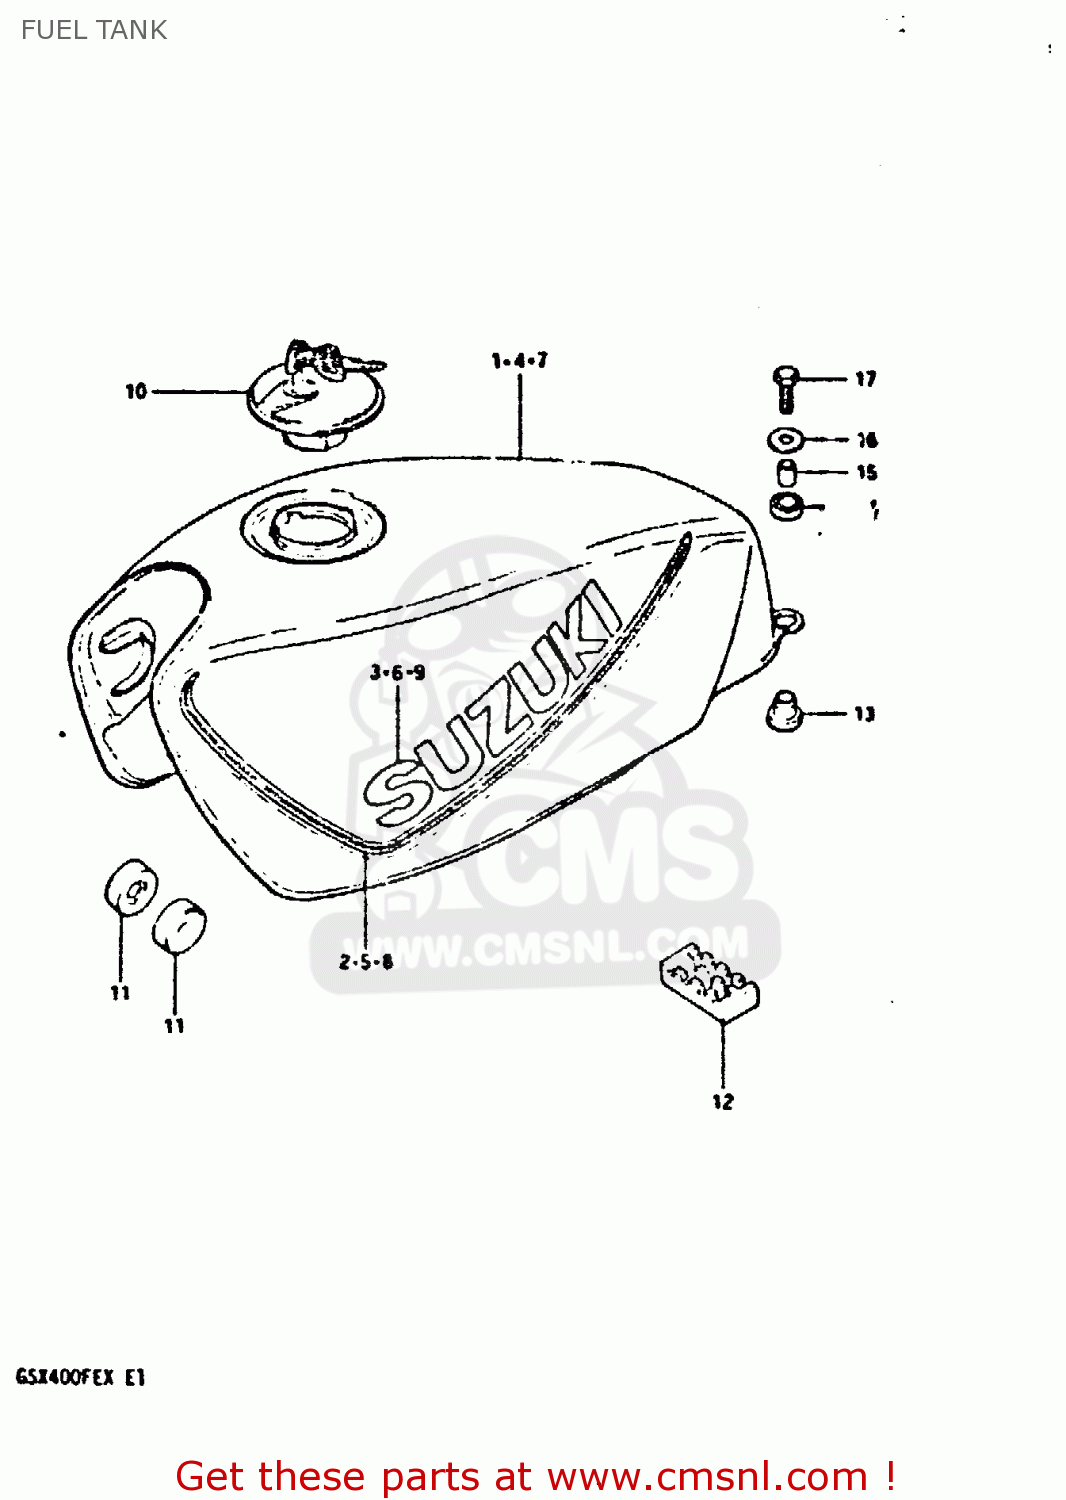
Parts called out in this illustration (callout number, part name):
1	TANK, FUEL (BLUE)
2	TAPE SET
3	EMBLEM,FUEL TANK
4	TANK, FUEL (SILVER)
5	TAPE SET
6	EMBLEM(ORANGE)
7	TANK, FUEL (RED)
8	TAPE SET
9	EMBLEM,FUEL TANK
10	CAP SET, FUEL
11	CUSHION
12	CUSHION,FUEL TANK CTR
13	CUSHION
14	CUSHION
15	SPACER
16	WASHER (6.5X24X1.6)
17	BOLT
